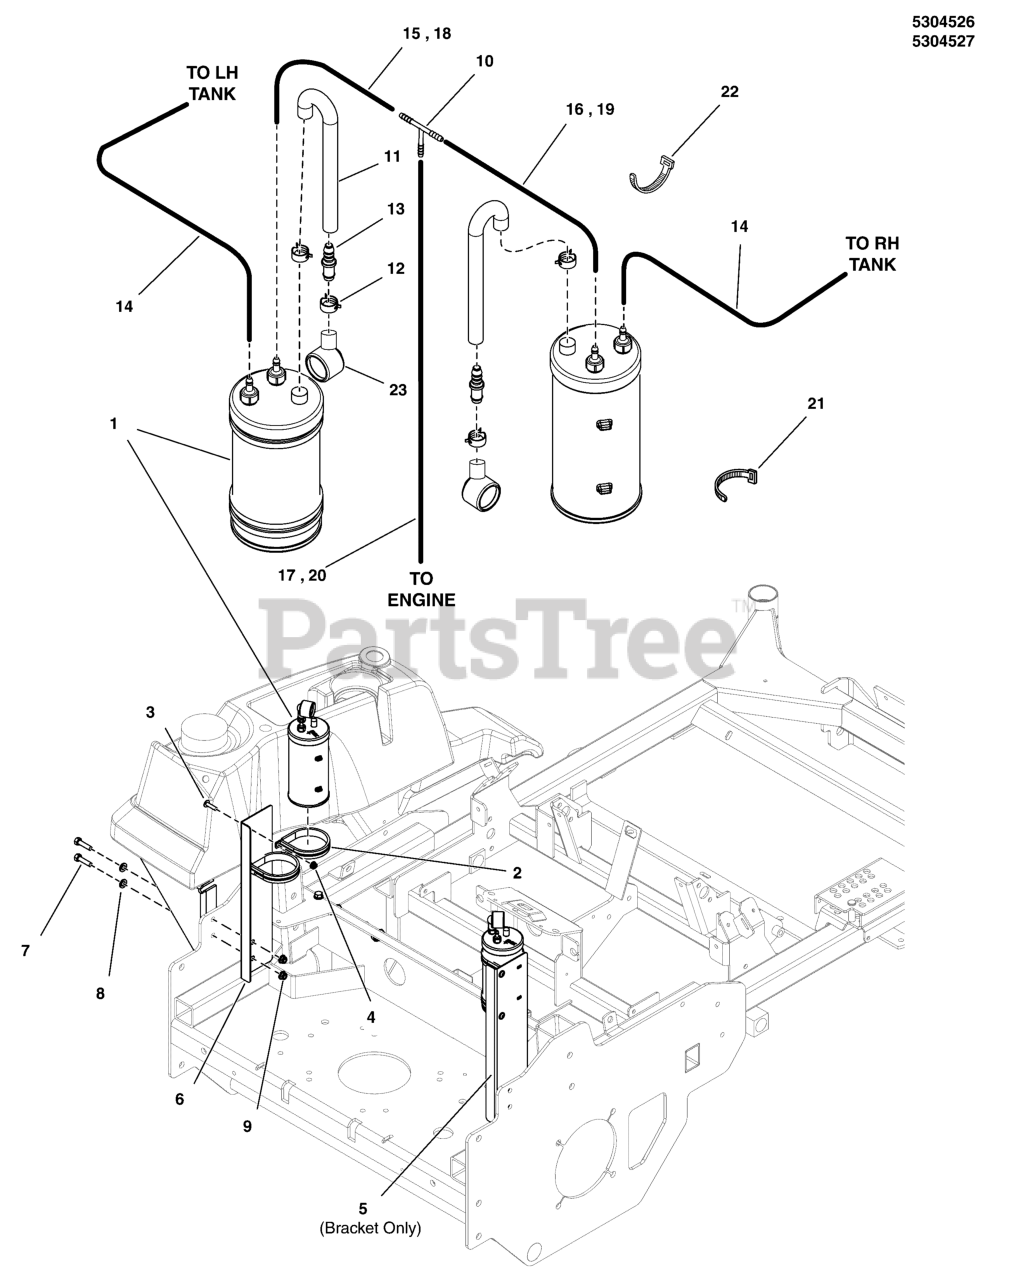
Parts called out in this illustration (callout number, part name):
1	CNSTR, CARB, 6 GAL
2	CLAMP, 3" ID, CUSHIONED, STAINLESS
4	NUT, 1/4-20 HEX NYLOCK FLANGE
5	PLATE, CARB CAN, S200XT, RH - BLK
6	PLATE, CARB CAN, S200XT, LH - BLK
7	BOLT, 5/16-18 X 1-1/4 GD5 CZ
8	WASHER, 5/16 LOCK CZ
9	NUT, 5/16-18 HEX NYLOCK FLANGE
10	FITTING, 3/16" TEE, BARB TYPE, HDPE
11	HOSE, FORMED, EVAP CANISTER
12	CLAMP, HOSE
13	FITTING, STRAIGHT, 10MMX10MM, PLASTIC
14	HOSE, VAPOR, 5MM ID, 10.00 LG
15	HOSE, VAPOR, 5MM ID, 50.50 LG
16	HOSE, VAPOR, 5MM ID, 29.00 LG
17	HOSE, VAPOR, 5MM ID, 9.00 LG
18	HOSE, VAPOR, 5MM ID, 18.50 LG
19	HOSE, VAPOR, 5MM ID, 47.00 LG
20	HOSE, VAPOR, 5MM ID, 24.00 LG
21	TIE, SELF-LOCKING, 15"
22	TIE, SELF-LOCKING, 12"
23	DUST FILTER, CANISTER
